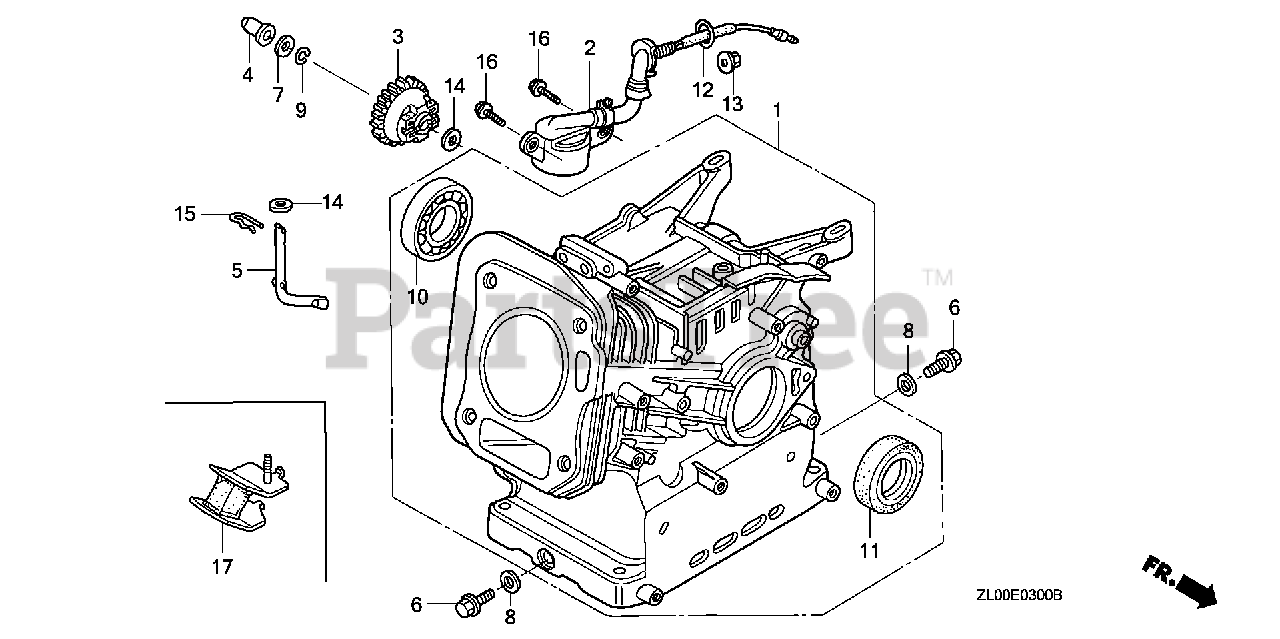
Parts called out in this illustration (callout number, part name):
1	CYLINDER ASSY.
2	SWITCH ASSY., OIL LEVEL
3	GOVERNOR ASSY.
4	SLIDER, GOVERNOR
5	SHAFT, GOVERNOR ARM
6	BOLT, DRAIN PLUG
7	WASHER, THRUST (6MM)
8	WASHER, DRAIN PLUG (10.2MM)
9	CLIP, GOVERNOR HOLDER
10	BEARING, RADIAL BALL (6205TMB) (NTN)
11	OIL SEAL (25X41X6)
12	O-RING (14MM) (ARAI)
12	O-RING (14MM) (NOK)
13	NUT, FLANGE (10MM)
14	WASHER, PLAIN (6MM)
15	PIN, LOCK (8MM)
16	BOLT, FLANGE (6X12)
